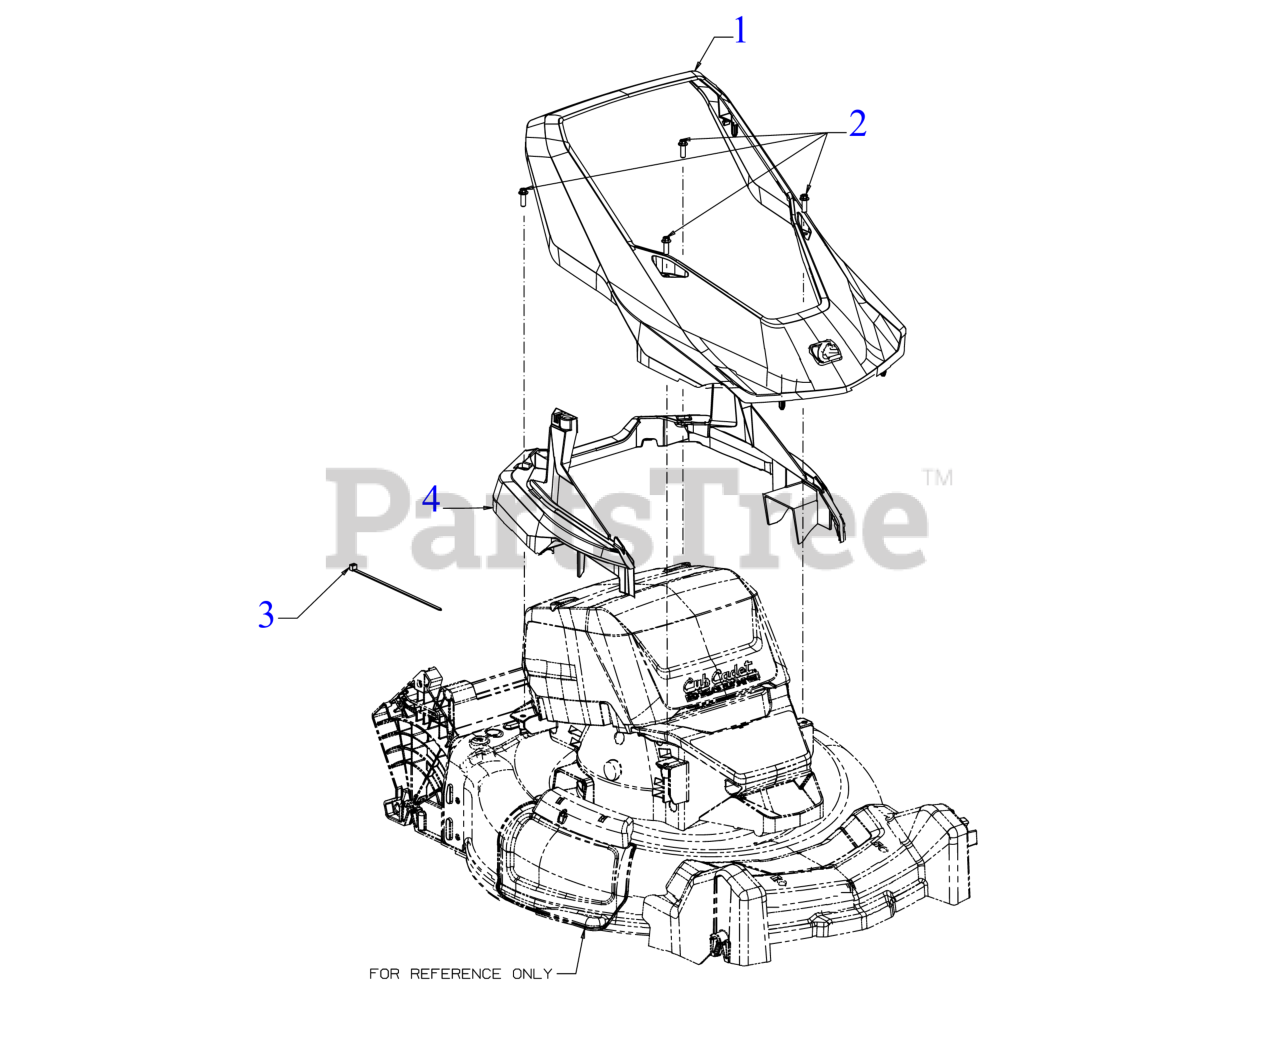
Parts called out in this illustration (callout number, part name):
1	MOTOR COVER (OUTER/UPPER)
2	SCREW 1/4 x .750
3	7" CABLE TIE
4	MOTOR COVER (OUTER/LOWER)
